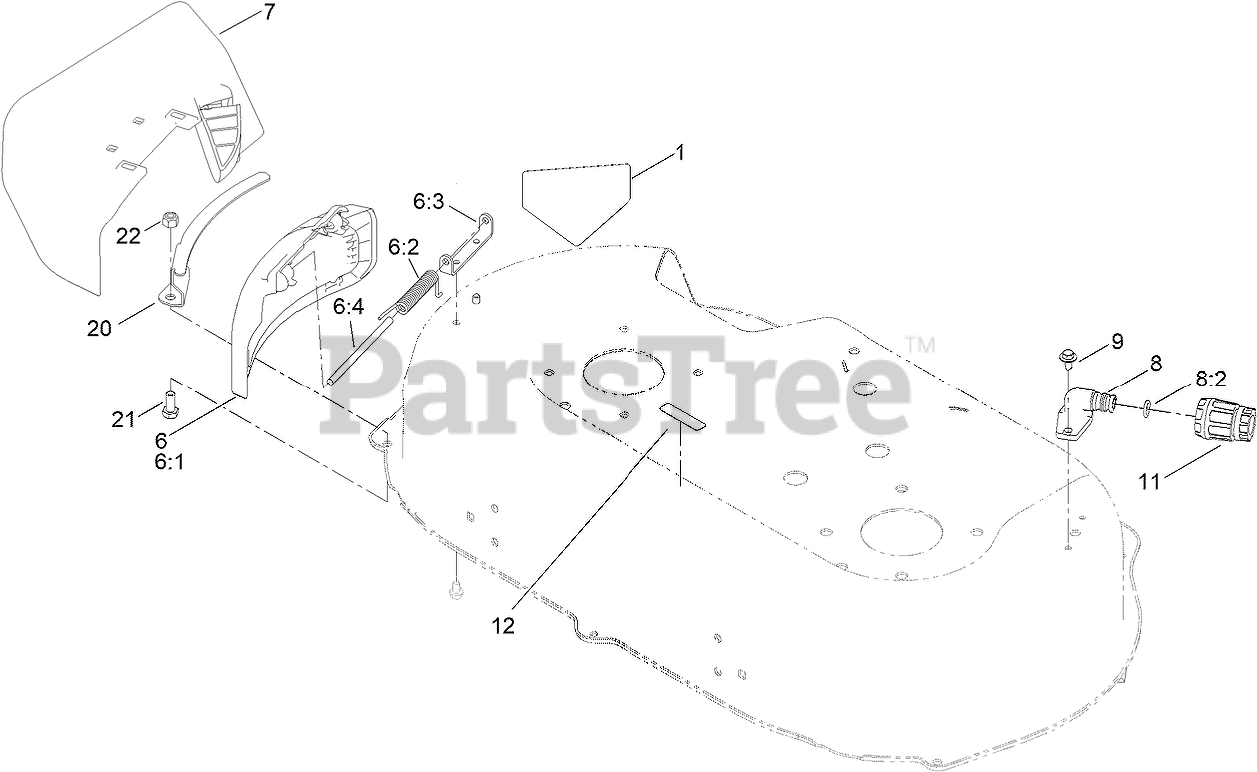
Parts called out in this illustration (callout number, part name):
1	DECAL-DANGER
6	SIDE DEFLECTOR SERVICE ASM
6:1	DEFLECTOR-SIDE
6:2	SPRING-TORSION, COVER
6:3	BRACKET-COVER
7	CHUTE-DISCHARGE, SIDE
8	FITTING-WASHOUT
8:2	O-RING
9	SCREW-HWH, THD ROLL
11	CONNECTOR-HOSE
12	DECAL-WARNING
20	BRACKET-DOOR, SIDE
21	SCREW-HH
22	NUT-LOCK, NI
